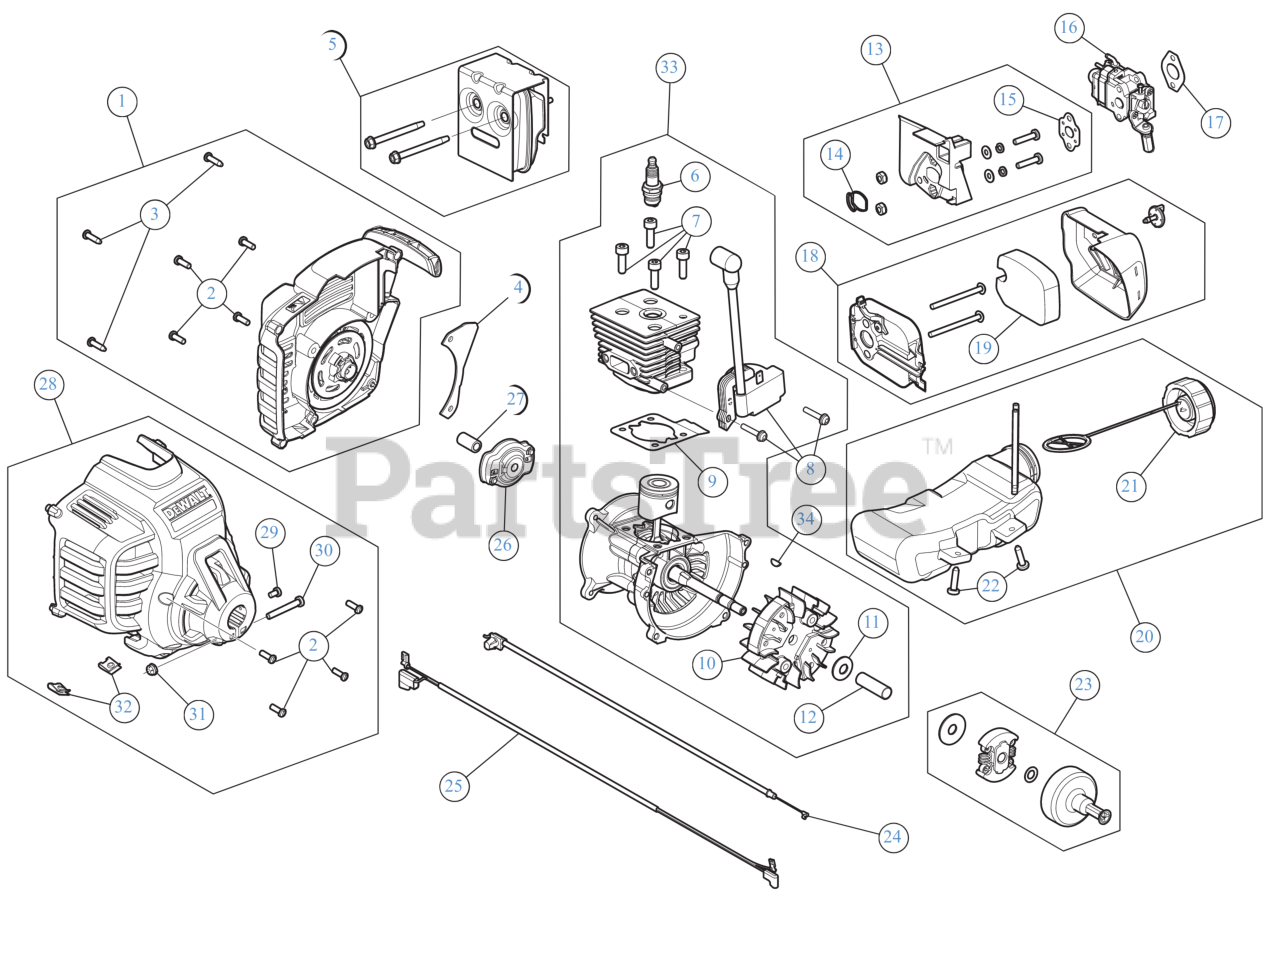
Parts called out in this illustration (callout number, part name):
1	STARTER HOUSING 27CC
2	SCREW #
3	SCREW 8-16 x 3/4
4	STARTER GUARD
5	MUFFLER ASSEMBLY
6	SPARK PLUG
7	SCREW 1/4 x 20 x .8125
8	MODULE 27CC
9	GASKET CYL
10	FLYWHEEL ASSEMBLY 27CC
11	BELL WASHER
12	SPACER
13	INTAKE ASSEMBLY
14	O-RING
15	CARBURETOR GASKET
16	CARBURETOR 27cc
17	GASKET CARB
18	AIR CLEANER
19	AIR FILTER
20	FUEL TANK
21	FUEL CAP
22	SCREW:10-6 x .75
23	SMALL CLUTCH ASSEMBLY W/SMALL DRUM
24	THROTTLE CABLE
25	LEAD WIRES
26	PAWL ASSEMBLY AC5
27	ELECTRIC START ADP
28	CLUTCH COVER
29	SCREW, 8-32 x .312 P
30	SCREW 10-24 X 1.12
31	HEX NUT
32	NUT, TINNERMAN U-T
33	SHORTBLOCK
34	WOODRUFF KEY #403-.125 x .375
